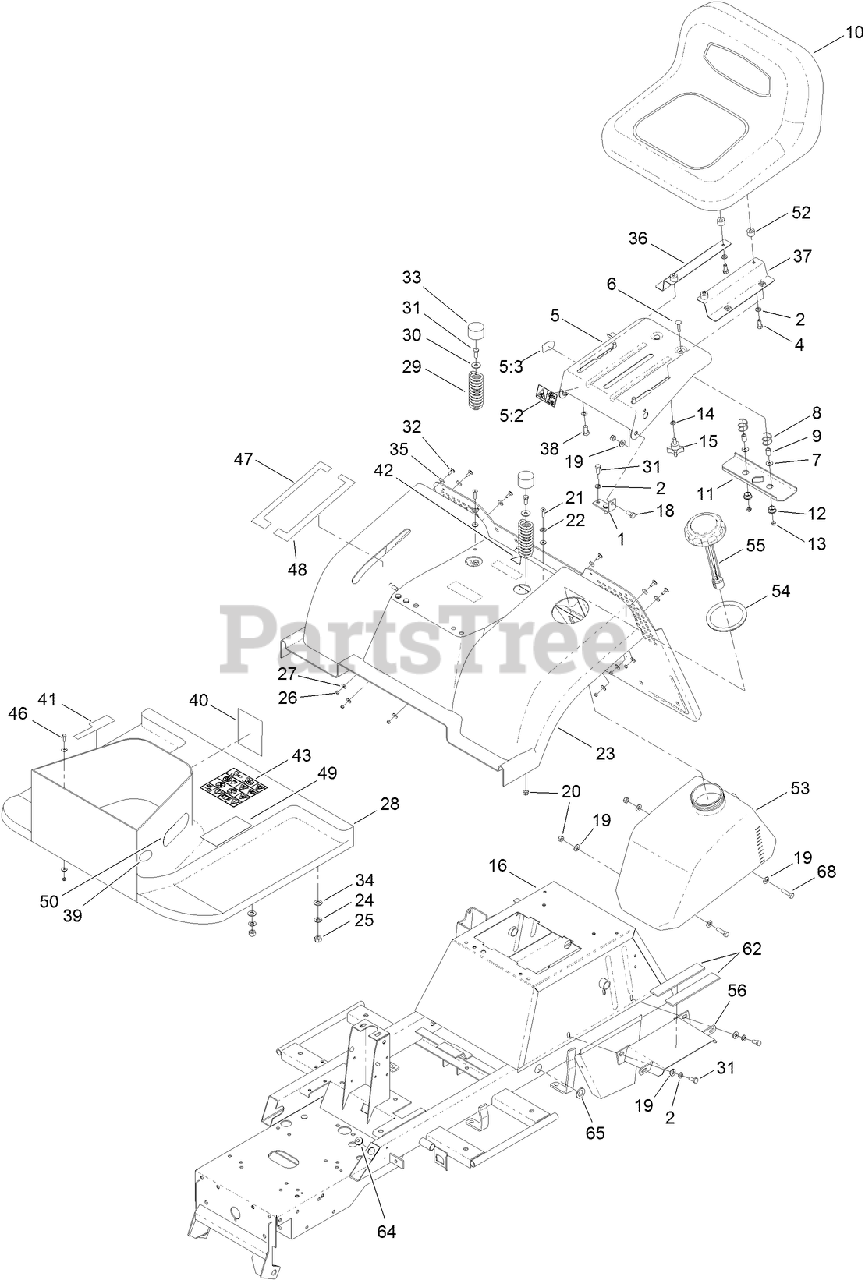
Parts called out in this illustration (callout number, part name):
1	BRACKET-SUPPORT, SEAT
2	WASHER-LOCK
4	SCREW-HH
5	SEAT PAN ASM
5:2	DECAL-DANGER
5:3	DECAL-SWITCH
6	BOLT-CARRIAGE
7	WASHER-FLAT
8	SPRING-SEAT
9	SPACER-SPLIT
10	SEAT ASM
11	BRACKET
12	BUSHING
13	NUT-LOCK
14	WASHER-SPRING
15	KNOB-ADJUSTMENT
16	FRAME KIT
18	SCREW-SUPPORT, SEAT
19	WASHER-PLAIN
20	NUT-LOCK, NI
21	SCREW-HSFH
24	WASHER-FLAT
25	NUT-LOCK, NI
26	NUT-LOCK
27	WASHER-FLAT
28	FOOTREST ASM
29	SPRING-SEAT
30	WASHER-PLAIN
31	SCREW-HH
32	BOLT-CARRIAGE
33	CAP-HUB
34	WASHER-RUBBER
35	WASHER-RUBBER
36	BRACKET-SEAT, RH
37	BRACKET-SEAT, LH
38	SCREW-HHF
39	DECAL-BRAKE, PARKING
40	DECAL-STARTING
41	DECAL-OPERATION, HYDRO
42	DECAL-BAG TO FRAME
43	DECAL-DANGER
46	SCREW-HH
47	DECAL-HOC, LH
48	DECAL-HOC, RH
49	DECAL-OPERATION
50	DECAL-TOWER
52	SHIM-SEAT
53	TANK-FUEL
54	PROTECTOR-NECK, FILLER
55	CAP-FUEL
56	BRACKET-TANK, FUEL
62	STRIP-RUBBER, FUEL TANK
64	GROMMET
65	GROMMET
68	SCREW-HH
